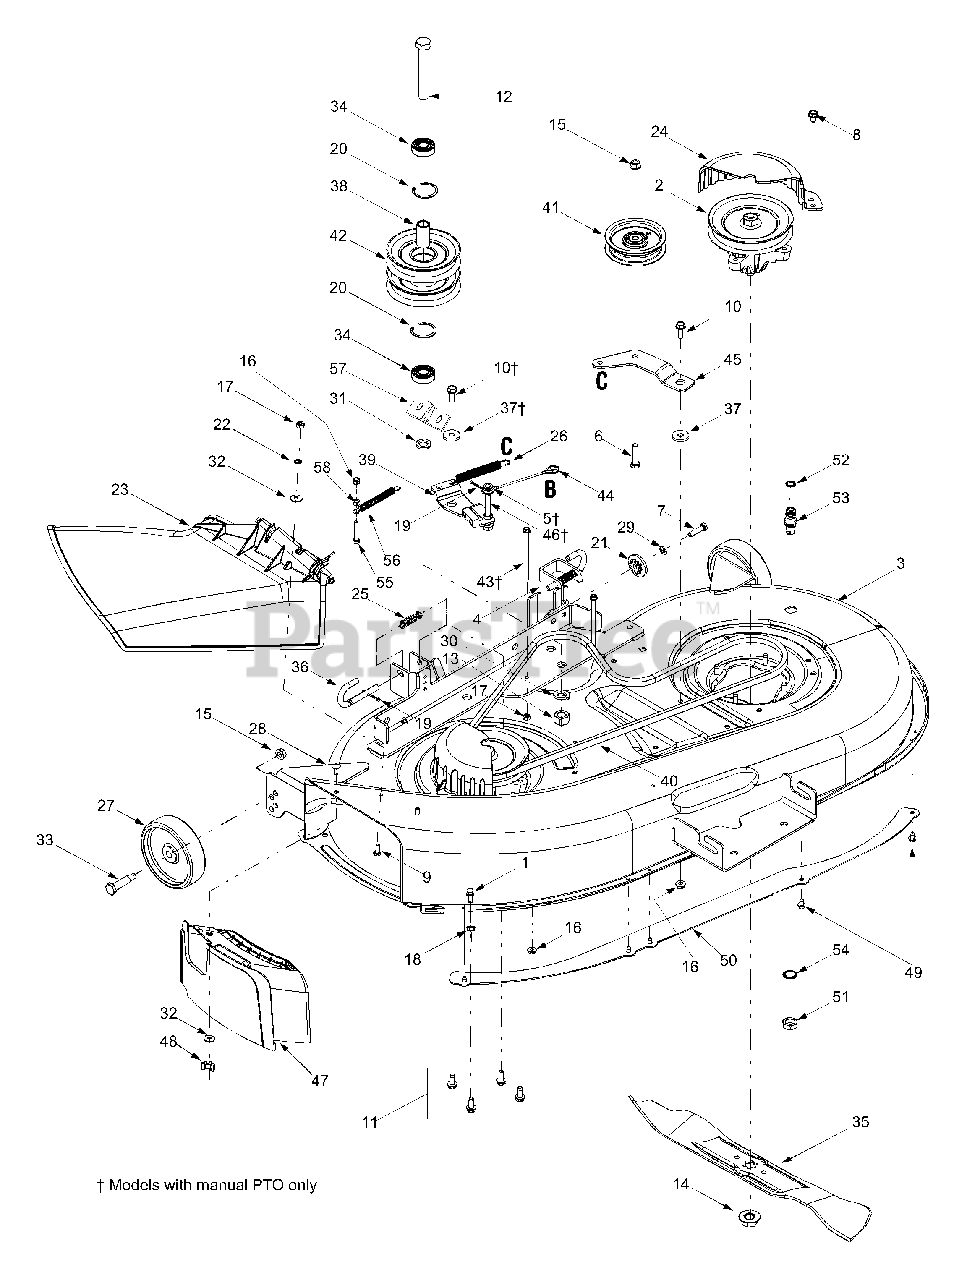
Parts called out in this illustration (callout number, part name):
1	Grass Catcher Pin, 1/4-20
2	Spindle Assy., 5.75 Dia. w/ Fitting
5	Flat Washer, .385 x .62 x .063
6	Hex Cap Screw, 1/4-20 x 1.5
7	Hex Cap Screw, 5/16-18 x 1.25
8	Self-tapping Screw, 5/16-12 x .75
9	Hex Cap Screw, 1/4-20 x .62
10	Hex Hd. Washer Scr., 5/16-18 x .875
11	Self-tapping Screw, 5/16-18 x .875
12	Hex Cap Screw, 5/8-18 x .875
13	Hex Nut, 5/8-18
14	Hex Flange Nut, 5/8-18
15	Flange Lock Nut, 3/8-16
16	Flange Lock Nut, 5/16-18
17	Hex Nut, 1/4-20
18	Hex Lock Nut, 3/8-16
19	Cotter Pin, 1/8 x 1.25
20	Internal Snap Ring
21	Deck Adjustment Gear
22	Push Nut. .25 x .5
23	Side Discharge Chute Assembly
24	Belt Cover
25	Comp. Spring, .406 x .531 x 1.75
26	Extension Spring, .50 x 4.74
27	Deck Wheel, 5 x 1.38
28	Carriage Screw, 1/4-20 x .5
29	Lock Washer, 5/16
30	Lock Washer, 5/8
31	Flat Washer, .64 x 1.0 x .12
32	Bell Washer, .265 x .75 x .062
33	Shoulder Screw, .498 x 1.53
34	Bearing, .625 x 1.574 x .470
35	Blade, Star Center, 21.23"
36	Deck Release Pin
37	Shoulder Spacer, .625 x .324
38	Spacer, .635 x .88 x 1.72
39	Deck Brake Assembly
40	Deck Belt
41	Idler Pulley, 3.5
42	Double Pulley, 5.0
43	Self-tapping Screw, 1/4-20 x 4.0
44	Brake Cable, 5.05
46	Pin, 3/8-16, 3/8 x 3.27
47	Mulch Plug
48	Wing Nut
49	Self-Tapping Screw, 1/4-20 x .5
51	Hex Nut, M-16 x 1.5
52	O-Ring
53	Water Nozzle (if equipped)
54	Lock Washer
55	Hex Bolt, 5/16-18 x 1.75
56	Extension Spring
58	Hex Nut
59	Chute Stop
